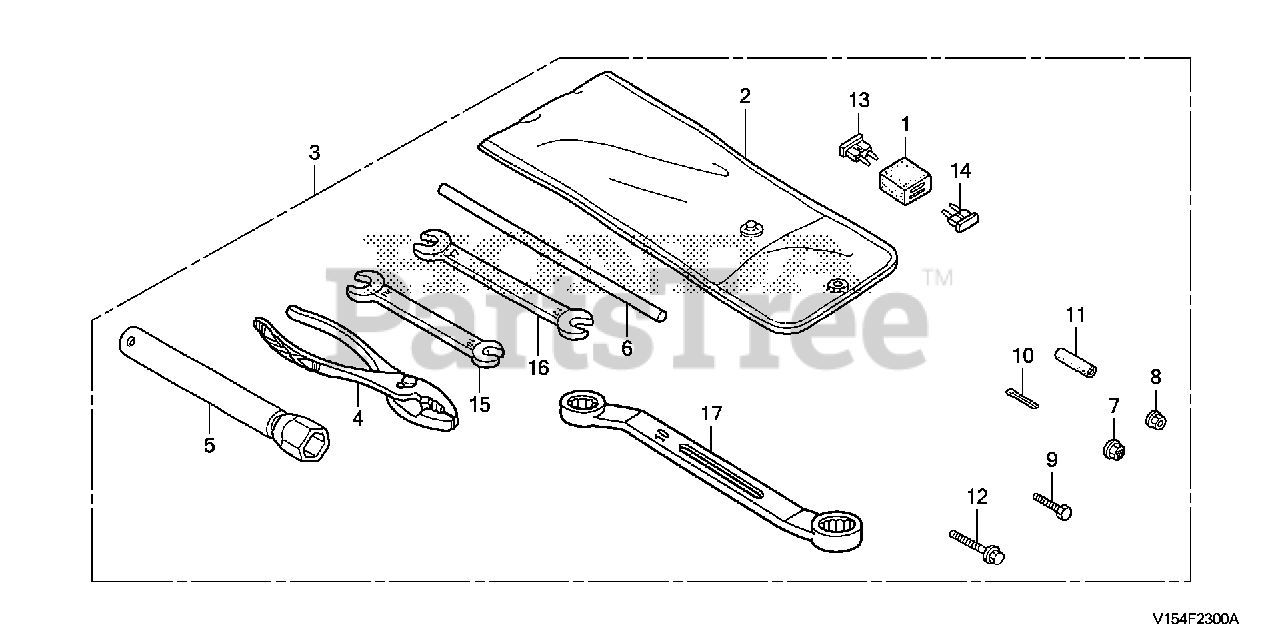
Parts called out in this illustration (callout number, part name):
1	SUSPENSION, TURN SIGNAL RELAY (MITSUBA)
2	BAG, TOOL
4	PLIERS (135) (RIKEN)
5	WRENCH, SPARK PLUG
6	HANDLE, BOX WRENCH (NOT AVAILABLE)
7	NUT, SELF-LOCK (8MM)
9	BOLT, HEX. (8X25)
10	PIN, COTTER (2.5MM)
11	BULK HOSE, VACUUM (17X1000) (17X27)
12	BOLT, FLANGE (8X25)
13	FUSE, MINI (5A)
14	FUSE, MINI (15A)
15	WRENCH (10X14) (OPEN END)
16	WRENCH (12X17) (OPEN END) (NOT AVAILABLE)
17	WRENCH, EYE (10X12)
